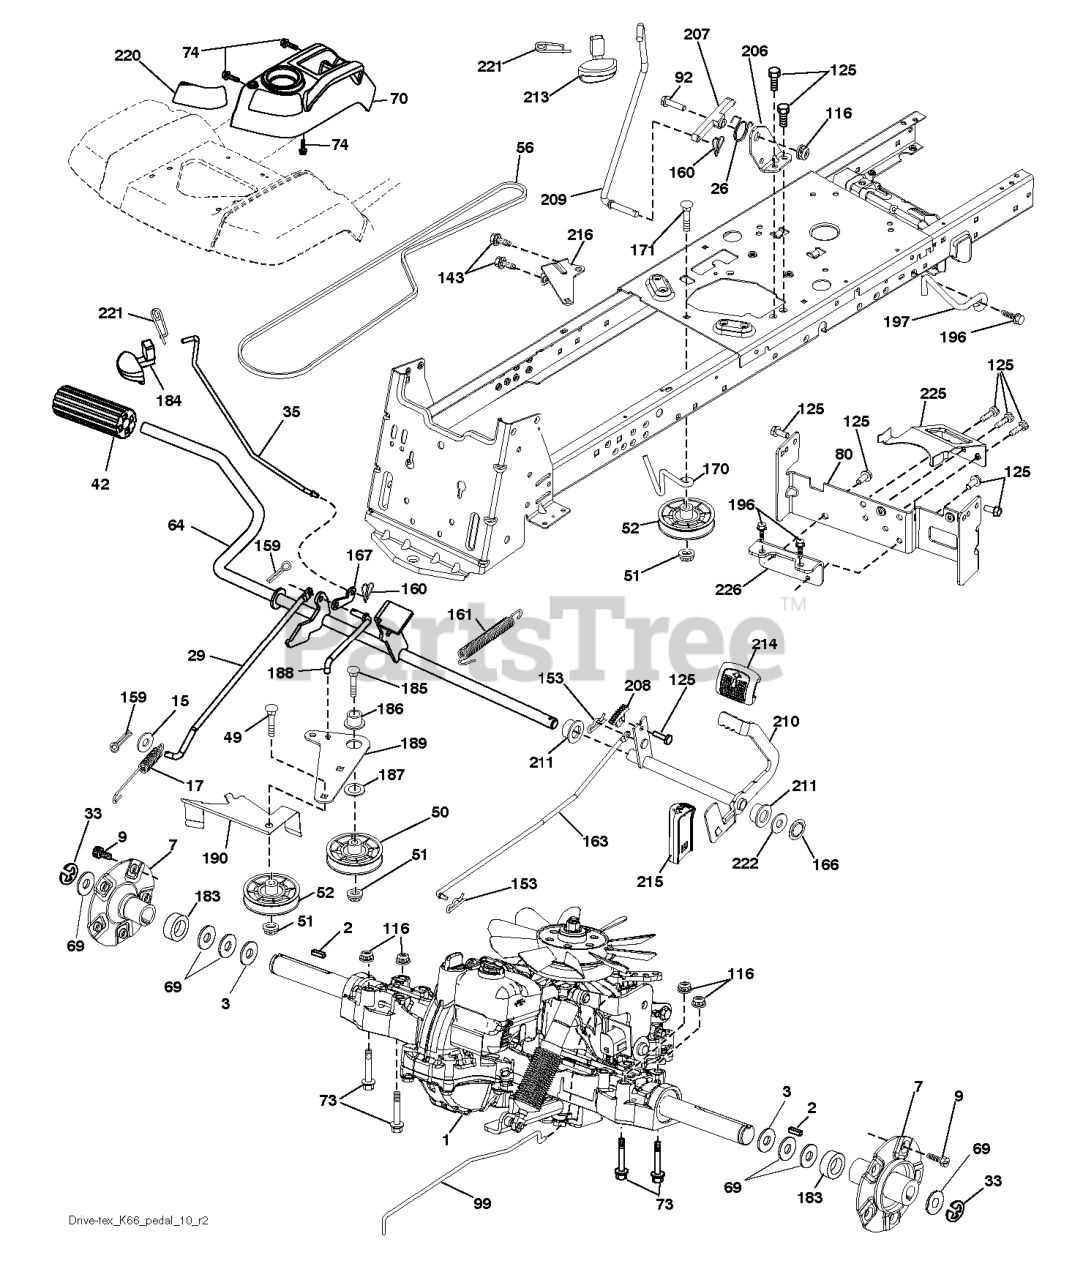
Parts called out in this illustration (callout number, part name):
2	KEY 1/4 X 2.5
7	HUB.ASM.WHEEL.REAR.23"TEX
9	HUB BOLT
15	WASHER
17	SPRING.BRAKE.K46
26	SPRING.RETURN.CRUISE
29	ROD.BRAKE.K66
33	E RING HYT
35	ROD.BRAKE.PARTK.HUSQ.TEX
42	PEDAL COVER T
50	IDLER.FLAT.910.OFFSET
51	NUT LOCK FLG 3/8-16 UNC
52	IDLER.V-GROOVE.910.OFFSET
64	SHAFT.ASM.PEDAL.BRK.CNTR
70	CONSOLE.ASM.RH.GT.FC.HUSQ
73	BOLT HEX 5/16-18 GR 5
74	SCREW.HI-LO.CONSOLE
80	STRAP.TORQUE.K66
92	BOLT
99	ROD.SPRING.BYPASS.K66.GT.Z
116	NUT LOCK HEX FLANGE 5/16-18
125	SCREW
143	SCREW LT
153	RETAINER M
159	COTTER PIN
160	RETAINER CLIP
161	SPRING, RETURN LT
163	ROD.PEDAL.CONTROL
166	NUT.PUSH.625
167	LATCH.BRAKE.SPRING
170	KEEPER.V-IDLER.CENTER.
171	BOLT
183	SPACER.AXLE.HG.TEX
184	RB HANDLE.PARKG.BRK.HUS/PRED
186	SPACER.RETAINER
187	WASHER 12/32X2X10GA
188	RP.LINK.CLUTCH.GROUND.DRIVE
189	BELLCRANK.GROUND.DRIVE.TEX.
190	KEEPER.BELLCRANK.DRIVE
196	SCREW 3/8-16X1
197	BRKT.ANIT-ROTATION.CLUTCH
206	BRACKET.MOUNT.CRUISE.LATCH
207	LATCH.CONTROL.CRUISE
208	GEAR.SECTOR.CONTROL.CR
209	ROD.CONTROL.CRUISE.GT.
210	ROCKER.ASM.PEDAL.CONTR
211	BEARING.NYLON
213	KNOB.CONTROL.CRUSIE.HU
214	PEDAL.FORWARD.PAD.TEX
215	PEDAL.REVERSE.TEX.GT.4
216	BRACKET.PULLEY.IDLER.W/TEX
220	REFLECTOR.RH.TEX GT
221	RETAINER.SPRING.CLIP.H
222	WASHER 21/32 X 1-1/4 X 10 GA.
225	KEEPER.BELT.TRANSAXLE.K66
226	BRACKET.MOUNT.TORQUE.K66.TG
